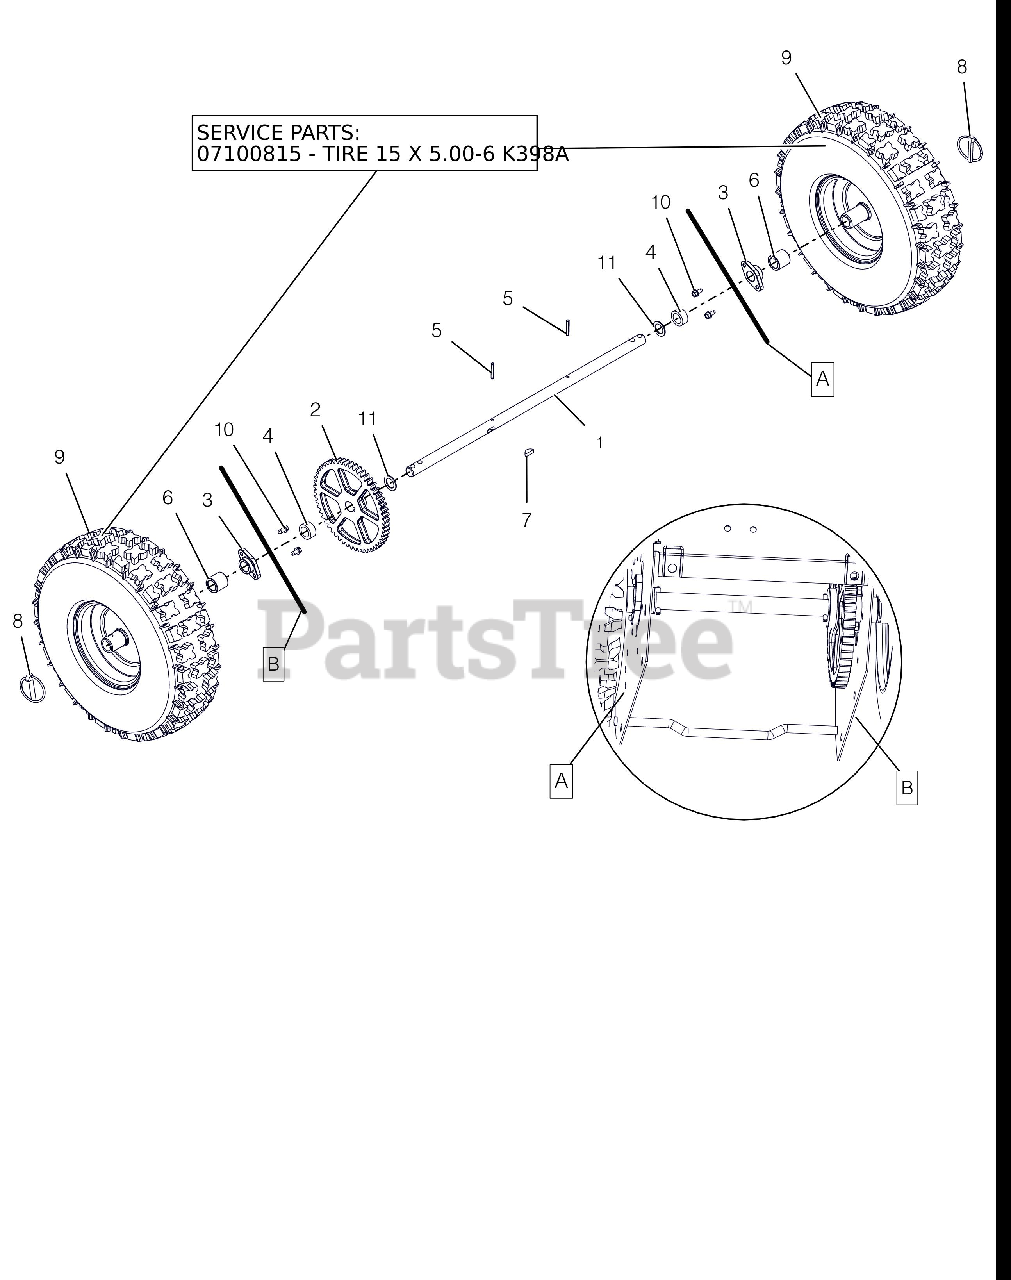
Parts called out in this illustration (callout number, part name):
1	AXLE, COMPACT 920,XXX 15" TIRE
2	SPUR GEAR, 54T .75ID X 6.75PD
3	BSHG .75X1.125X.65
4	BSHG-SLV .766 X 1.125 X .500
5	PIN-ROLL .188X1.25
6	BSHG-SLV .75X1.12X1.062 NYL BK
7	KEY-WDRF .25X.750X.313 SAE91
8	PIN-LOK .31X1.75
9	TIRE/WHEEL, 15X5.00-6 K398A
9	TIRE, 15" K398A
10	SCR-TAP .25-20X.50 HWH TR YWZ
11	WSHR-FL-STL.754X1.125X.062YWZC
